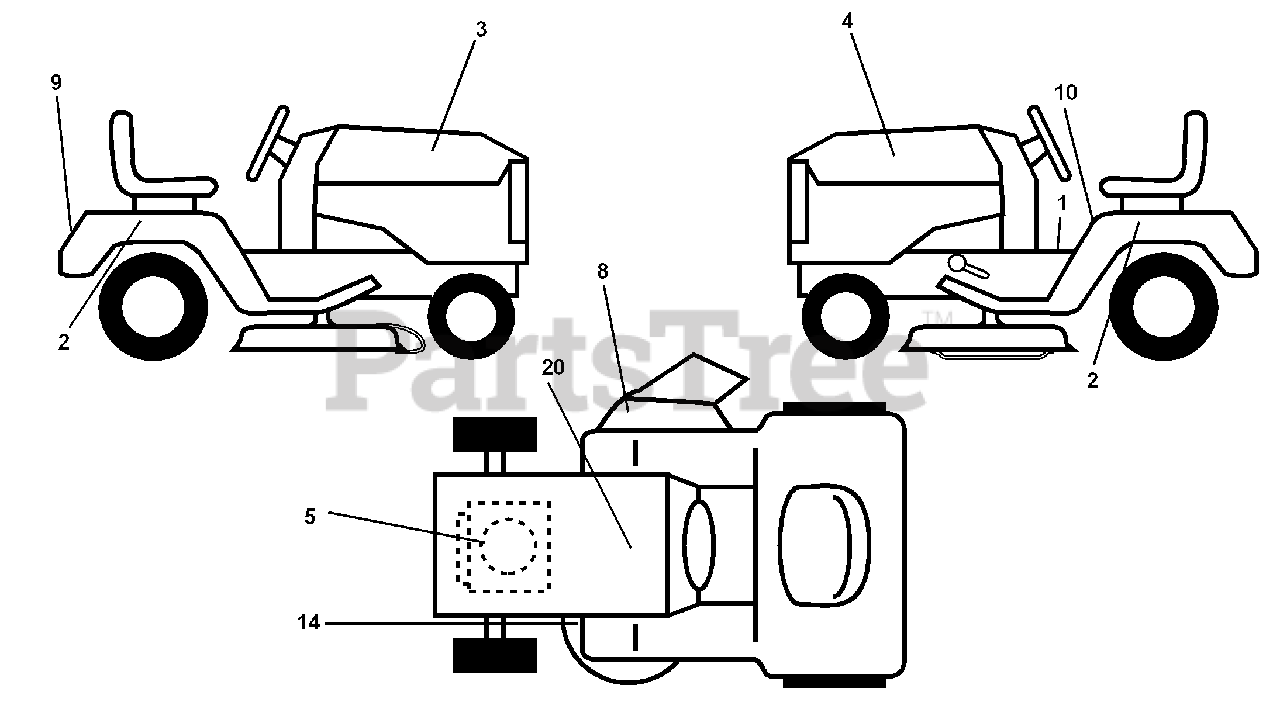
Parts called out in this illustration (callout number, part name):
1	Decal Oper Step Thru E/F
2	Decal Fender Auto Husq. Radius
3	Decal Hood RH
4	Decal Hood LH
5	Decal Engine
8	Decal Warning
9	Decal Fender Husq
10	Decal Fender Danger E/F
14	Decal V-Belt Schematic
20	Decal Bat Dan/Psn
20	Decal Drawbar Cntrl Mvt Hyd Lt
20	Pad Footrest LH STLT
20	Pad Footrest RH STLT
20	Decal Handle Lft Height Adjust
20	Manual Owner's
20	42" Snow Blower
20	Wheel Wts
20	Grass Catcher
20	48" Snow Blade
20	Tire Chains
